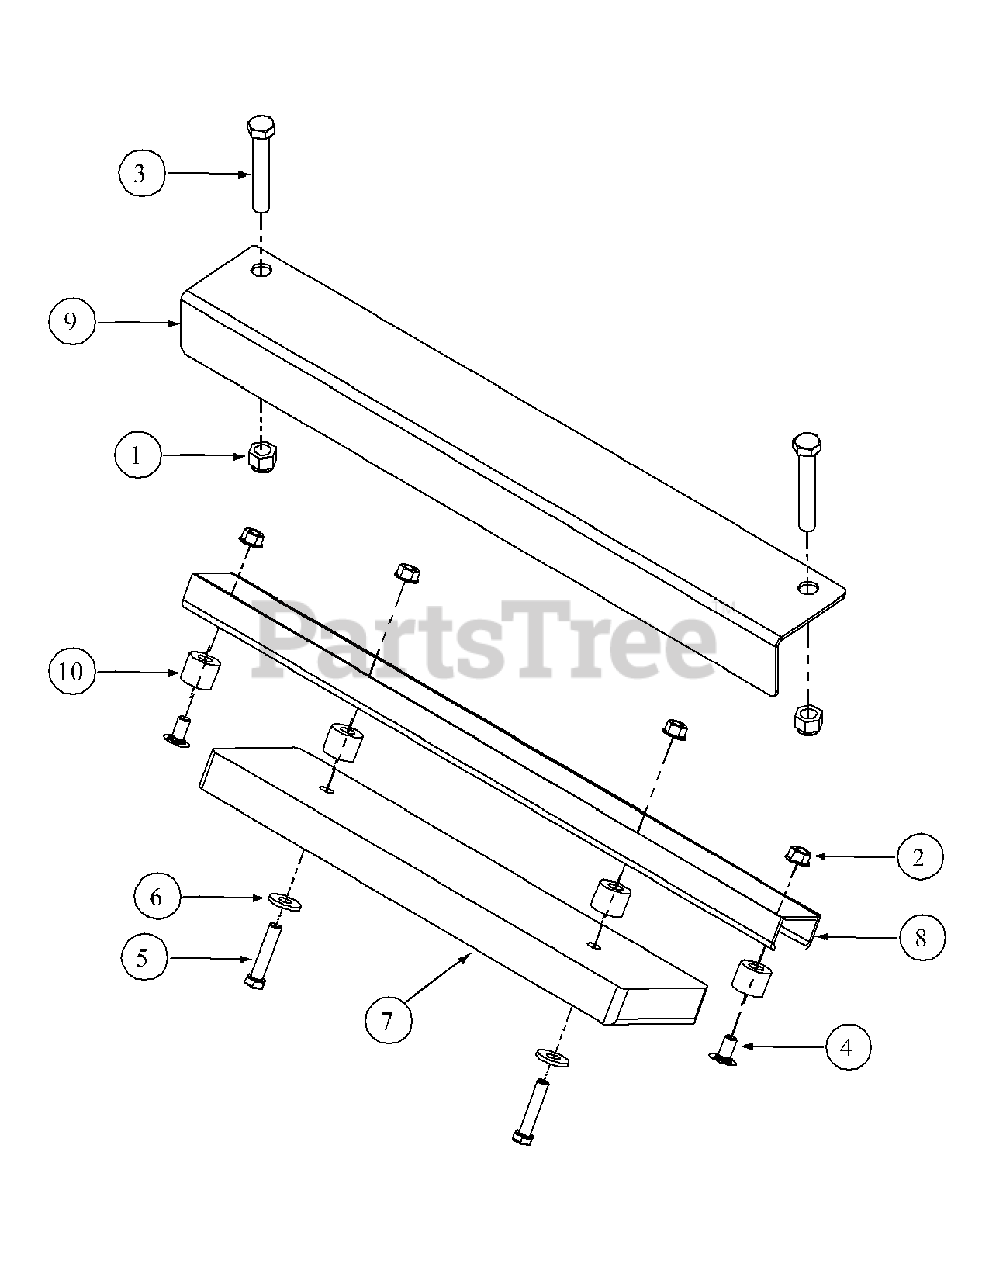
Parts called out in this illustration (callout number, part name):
1	Hex Nut, 1/2-13, Insert Lock
2	Nut, Hex 3/8-16 Flange Lock
3	HHCS, 1/2-13, 3.00
4	Carriage Bolt, 3/8-16 x 1.75
5	Hex Cap Screw, 3/8-16, 2.75
6	Flat Washer, .406 ID x 1.0 OD x .105
8	Bumper Cross Bar
9	Rear Bumper Bracket
10	Spacer
